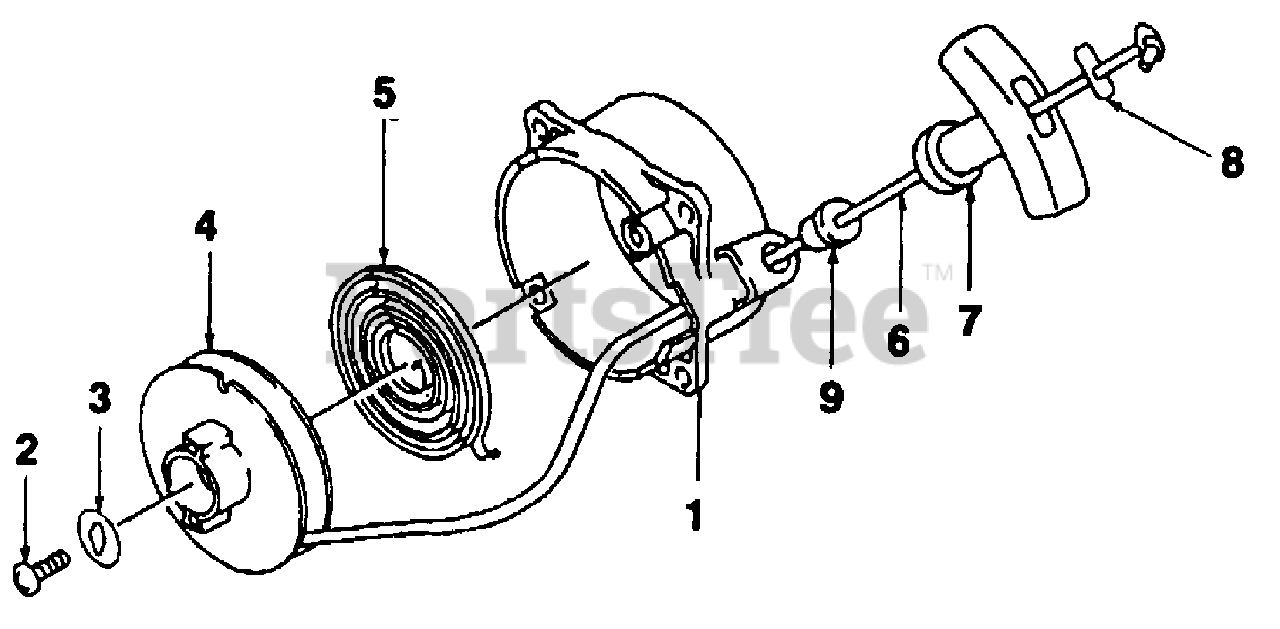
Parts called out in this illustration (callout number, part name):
1	RECOIL STARTER ASSY.
4	REEL Recoil
5	SPRING- Recoil
6	ROPE- (3.5 X 850)
7	HANDLE- Recoil
9	GUIDE- Rope
